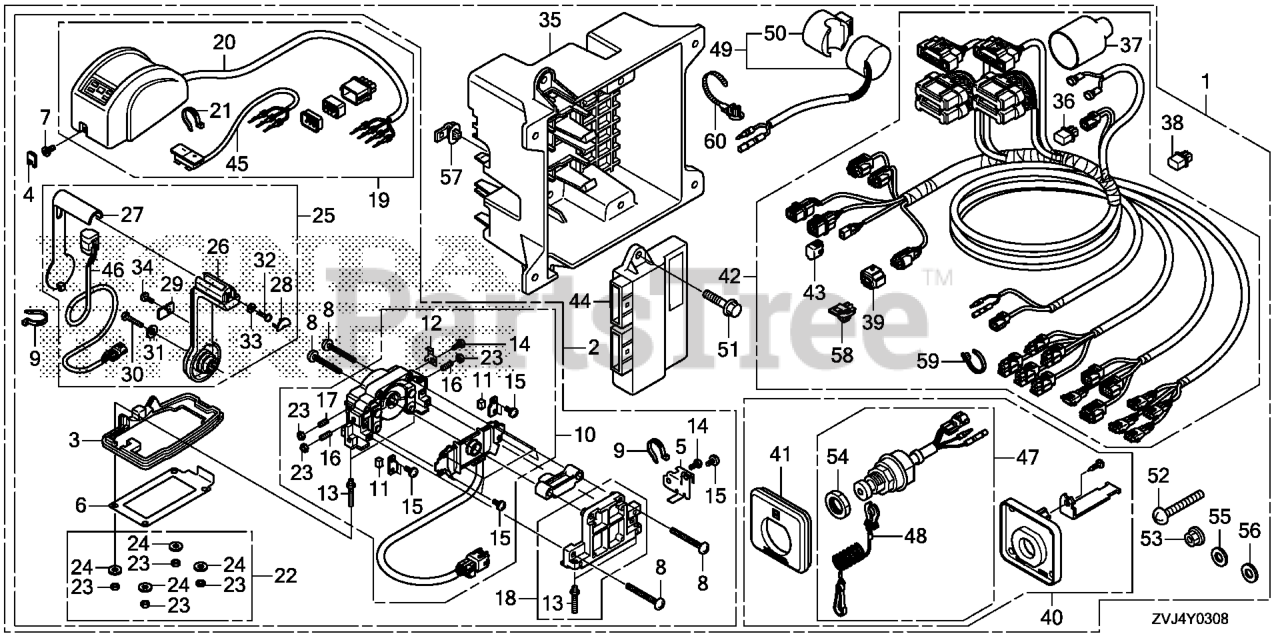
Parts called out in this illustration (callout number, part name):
1	BOX KIT, REMOTE CONTROL (2ND) (TOP MOUNT SINGLE)
1	BOX KIT, R/C (2ND)
2	BOX ASSY., REMOTE CONTROL (TOP MOUNT SINGLE)(RH)
3	GASKET (SINGLE)
4	COVER, CAP
5	PLATE, COVER FIX (SINGLE)
6	SHEET, WATERPROOF (SINGLE)
7	BOLT, SOCKET
8	SCREW
9	BAND, NYLON
10	HOUSING ASSY., L.
11	SHOE, BRAKE
12	PLATE, HARNESS
13	BOLT, STUD
14	BOLT
15	SCREW
16	SCREW SET
17	SCREW SET
18	HOUSING ASSY., SINGLE
19	COVER ASSY., SINGLE
20	LED ASSY., COVER (S)
21	BAND, NYLON
22	NUT SET, MOUNTING
23	NUT
24	WASHER
25	LEVER ASSY., L.
26	LEVER
27	PANEL, LEVER (POWER TRIM-TILT)
28	CAP, LEVER
29	PLATE, LEVER PANEL
30	BOLT
31	WASHER
32	SCREW
33	WASHER
34	SCREW
35	CASE, CONTROL UNIT
36	TERMINATOR ASSY.
37	COVER, CONNECTOR (NOT AVAILABLE)
38	DUMMY, WATERPROOF CONNECTOR
39	SUSPENSION, CONNECTOR
40	PANEL ASSY., EMERGENCY STOP
41	PANEL, EMERGENCY STOP SWITCH
42	CABLE ASSY., REMOTE CONTROL (2ND)
43	CAP, DUMMY (WPC 4P 090 M) (RED)
44	CONTROL UNIT
44	UNIT ASSY., CONTL
45	SWITCH ASSY., SELECT
46	SWITCH ASSY., POWER TRIM-TILT
47	SWITCH ASSY., EMERGENCY STOP
48	WIRE, EMERGENCY
49	BUZZER ASSY., WARNING
50	SUSPENSION, WARNING BUZZER
51	BOLT, FLANGE (6X20)
52	SCREW, PAN (5X40) DUAL QTY = (8) (SINGLE)
53	NUT, FLANGE (5MM)
54	NUT
55	WASHER, PLAIN (5MM)
56	WASHER, SPRING (5MM)
56	WASHER, SPG (5MM)
57	CLIP, CONNECTOR (DARK BLUE)
58	CLIP, CONNECTOR (DARK BROWN)
59	CLIP, HARNESS BAND (145MM) (BLACK)
60	CLIP, BAND HARNESS (152.4MM) (BLACK)
